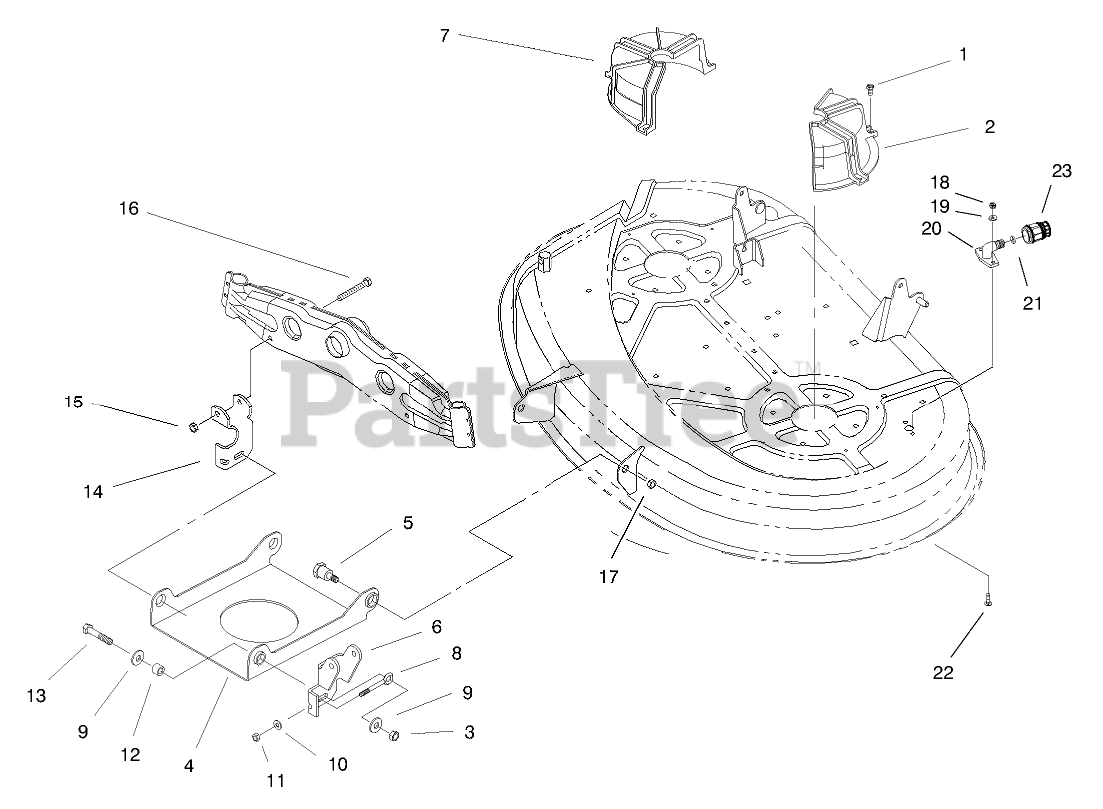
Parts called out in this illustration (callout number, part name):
1	SCREW-HWHTF
2	GUIDE-BELT, LH
3	NUT-LOCK, NI
4	PAN-DECK SUSPENSION, FRONT
5	BOLT-SHOULDER, HH
6	BRACKET-SUSPENSION, LH
7	GUIDE-BELT, RH
8	SCREW-ADJUSTING
9	WASHER-HARDENED
10	WASHER-FLAT
11	NUT-LOCK, NI
12	SPACER
13	SCREW-HH
14	BRACKET-SUSPENSION, RH
15	NUT-LOCK, NI
16	SCREW-HH
17	NUT-LOCK, NI
18	NUT-LOCK, NI
19	WASHER-FLAT
20	FITTING-WASHOUT
21	O-RING
22	BOLT-CARR
23	CONNECTOR-HOSE
